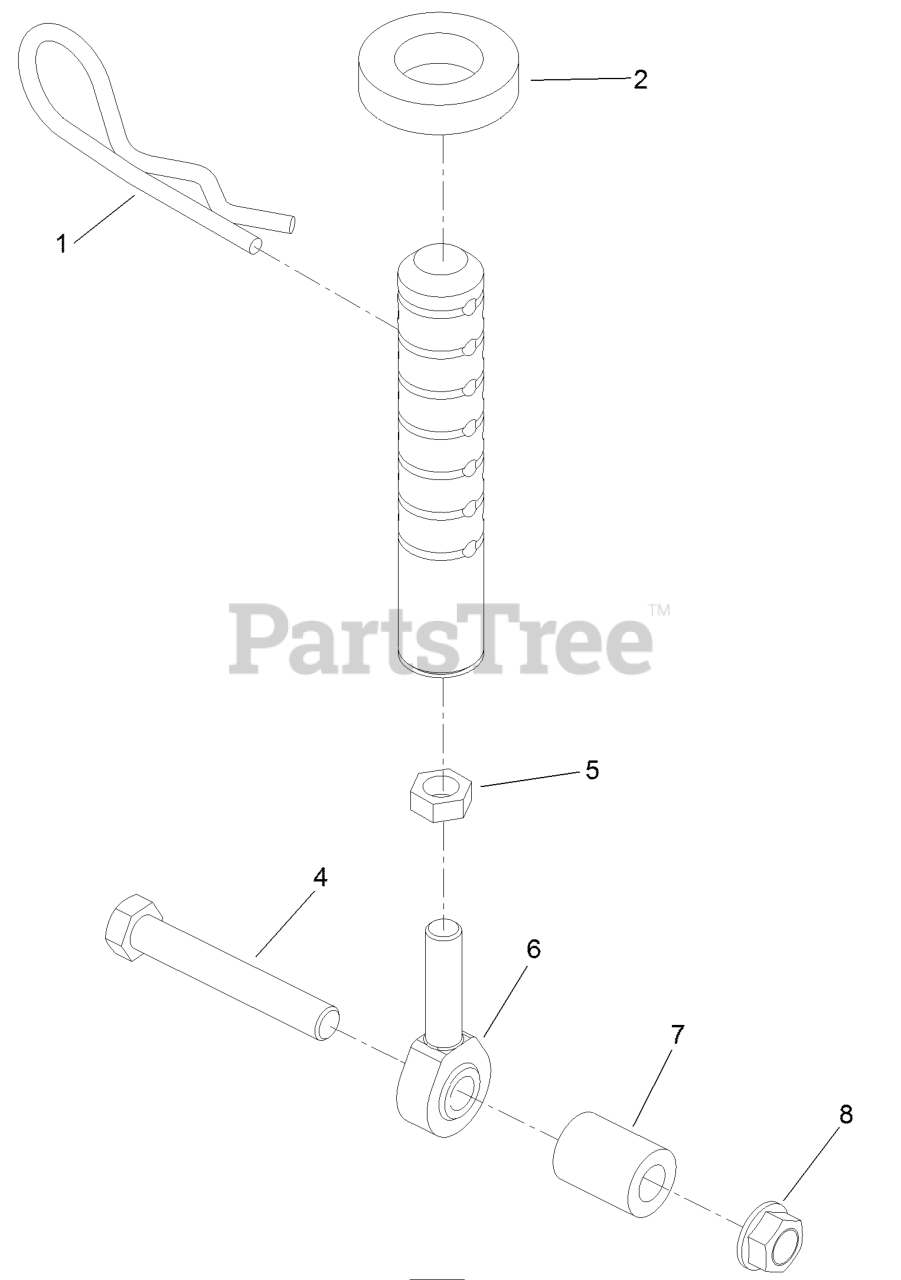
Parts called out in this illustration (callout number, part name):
1	PIN-CUT HEIGHT
2	SPACER-DECK SUPPORT
4	SCREW-HH
5	NUT-HJ
6	BALLJOINT
7	TUBE-INTERLOCK
8	NUT-HHF, WHIZ
